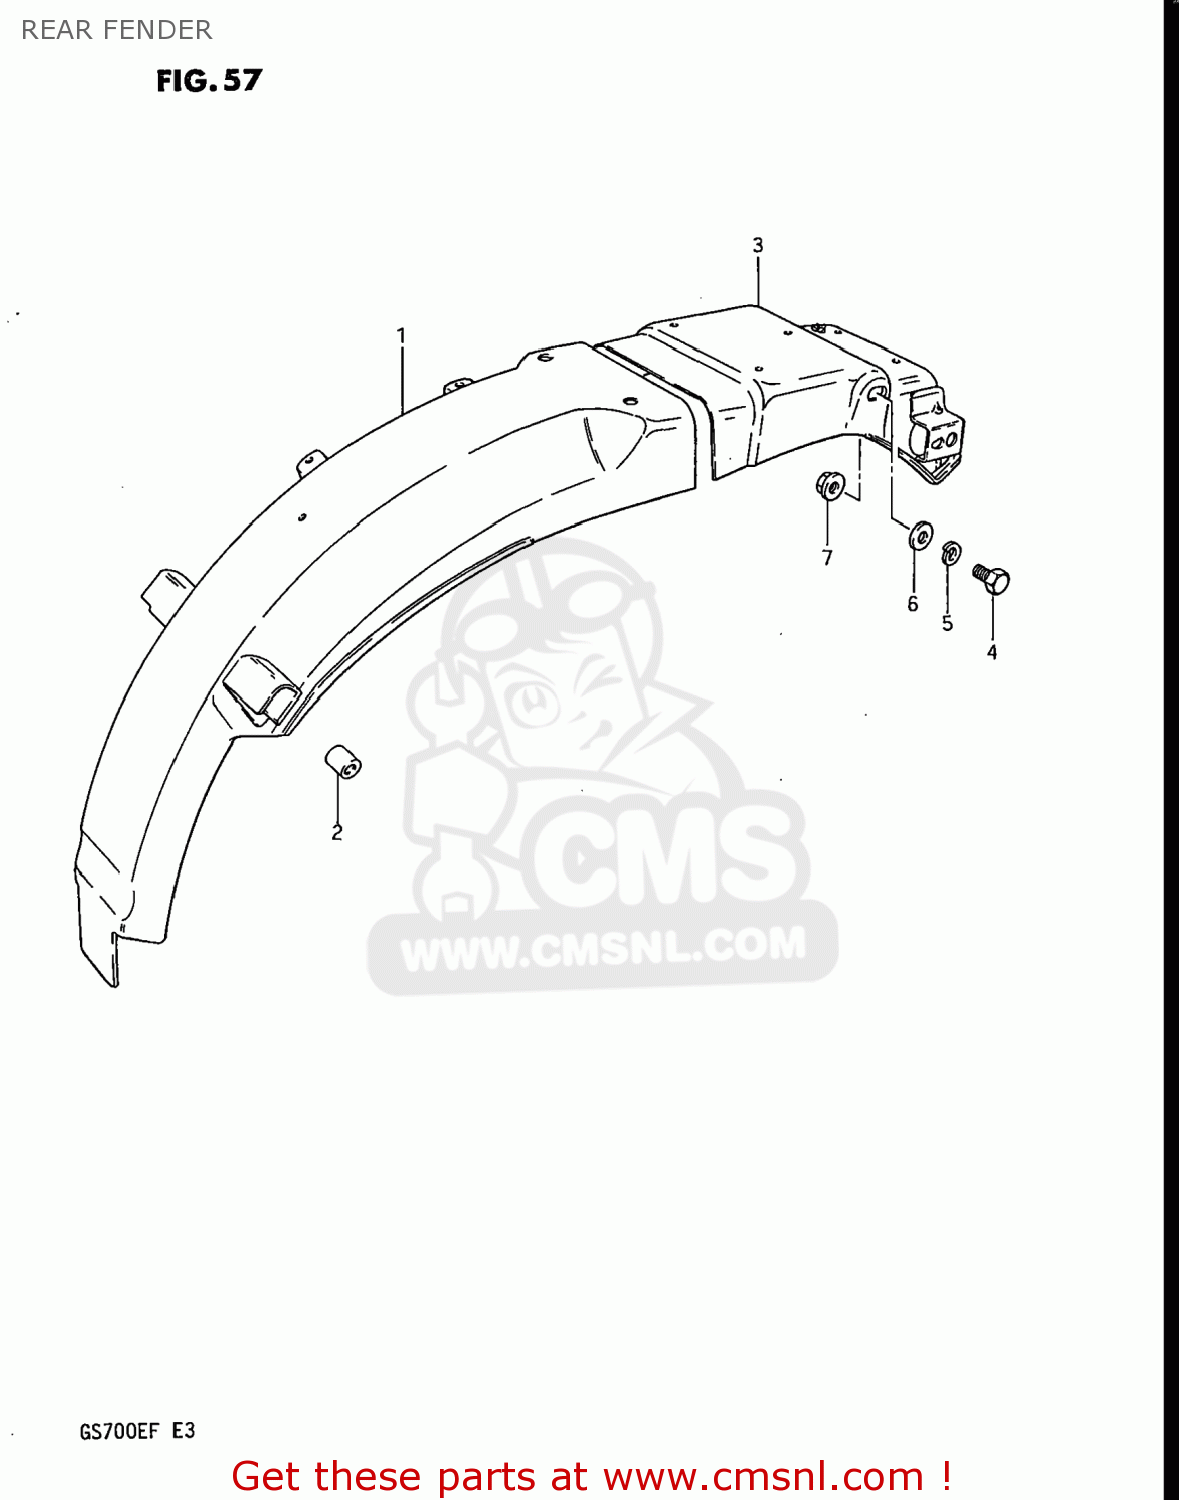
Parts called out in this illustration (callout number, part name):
1	BODY,REAR FENDER,FRONT
2	CUSHION
3	REINFORCEMENT,RR FENDER
4	BOLT,8X1.25X2
5	WASHER,LOCK,8.
6	WASHER 8MM
7	NUT, WHEEL SET
